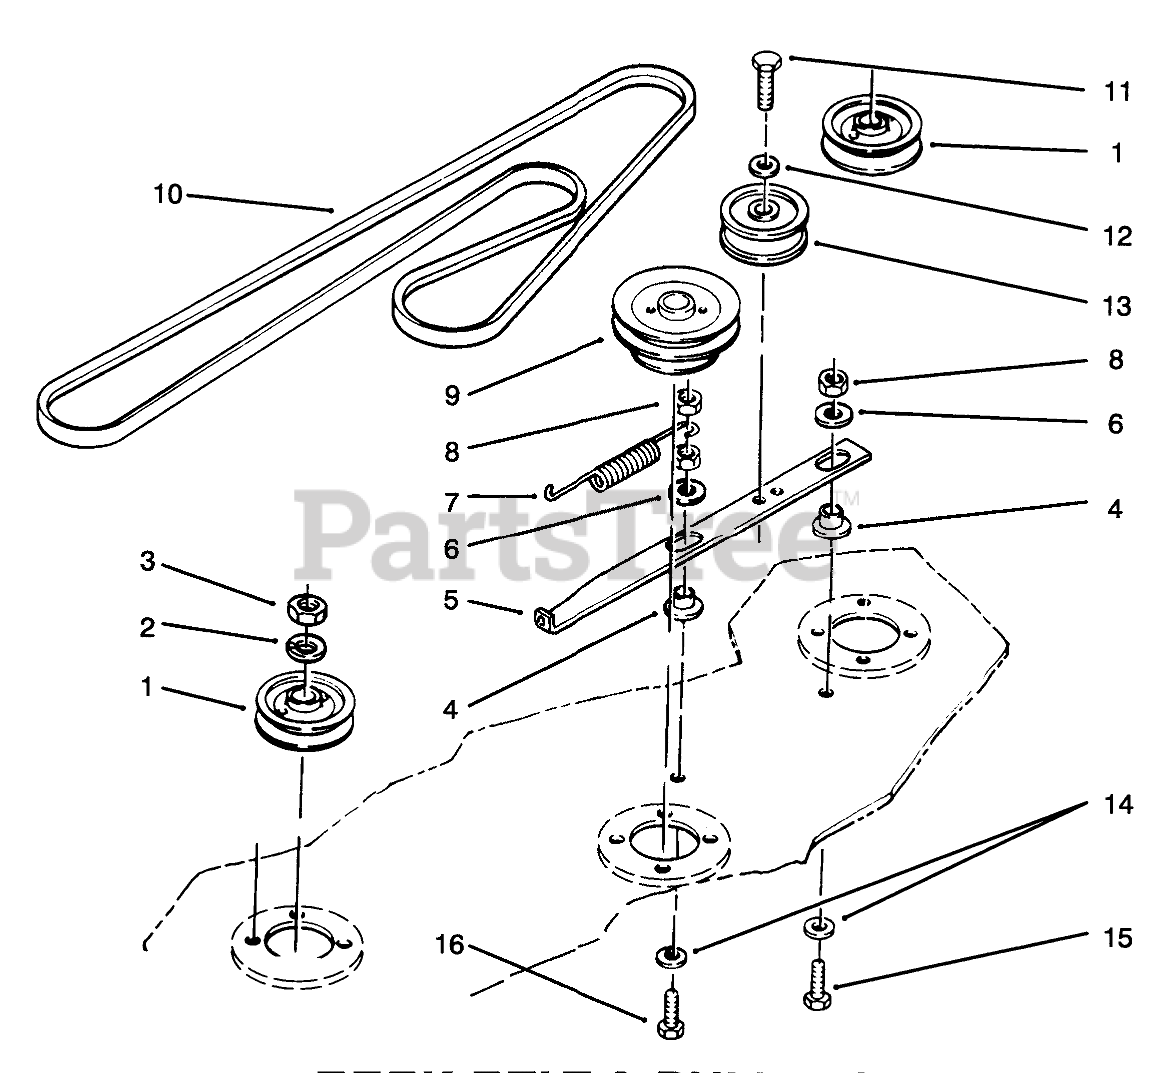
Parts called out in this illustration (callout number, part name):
1	PULLEY
2	WASHER-LOCK
3	NUT-JAM
4	SPACER-BUSHING
5	BAR-IDLER SUPPORT
6	WASHER
7	SPRING-EXTENSION
8	NUT-LOCK, NI
9	PULLEY
10	V-BELT
11	SCREW-HH
12	WASHER-LOCK
13	Idler Pulley
14	WASHER
15	SCREW-HH
16	SCREW-HH
